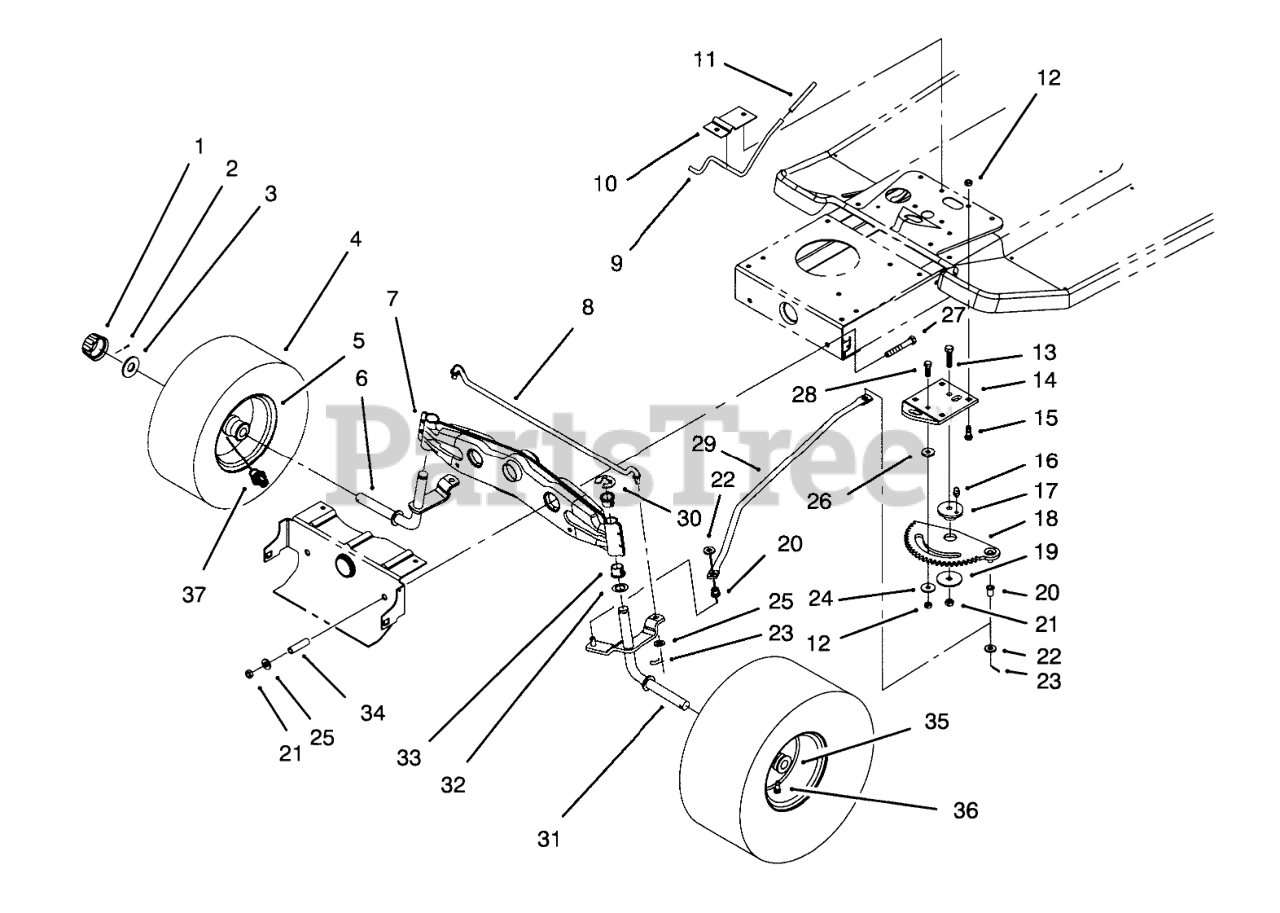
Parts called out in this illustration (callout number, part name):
1	CAP-HUB
2	PIN-COTTER
3	WASHER-PLAIN
4	TIRE 15 X 6.00 X 6
5	RIM ASM
6	Spindle-R.H.
7	Axle-Front
8	TIE ROD-STEERING
9	ROD-BRAKE, PARKING
10	Bracket-Parking Brake
11	GRIP-BRAKE, PARKING
12	NUT-LOCK, NI
13	SCREW-CARR
14	Bracket-Steering Rack
15	BOLT-CARR
16	FITTING-GREASE
17	BUSHING-ECCENTRIC
18	RACK-STEERING
19	WASHER-BEARING
20	BUSHING-FLANGED, NYLON
21	NUT-LOCK, NI
22	WASHER-FLAT
23	PIN-COTTER
24	WASHER-PIVOT
25	WASHER-FLAT
26	SPACER-RACK, STEERING
27	SCREW-HH
28	SCREW-CARR
29	LINK-DRAG
30	E-RING
31	Spindle-L.H.
32	WASHER-THRUST
33	BUSHING
34	SPACER
35	BEARING-WHEEL
36	STEM-VALVE
37	FITTING-GREASE
